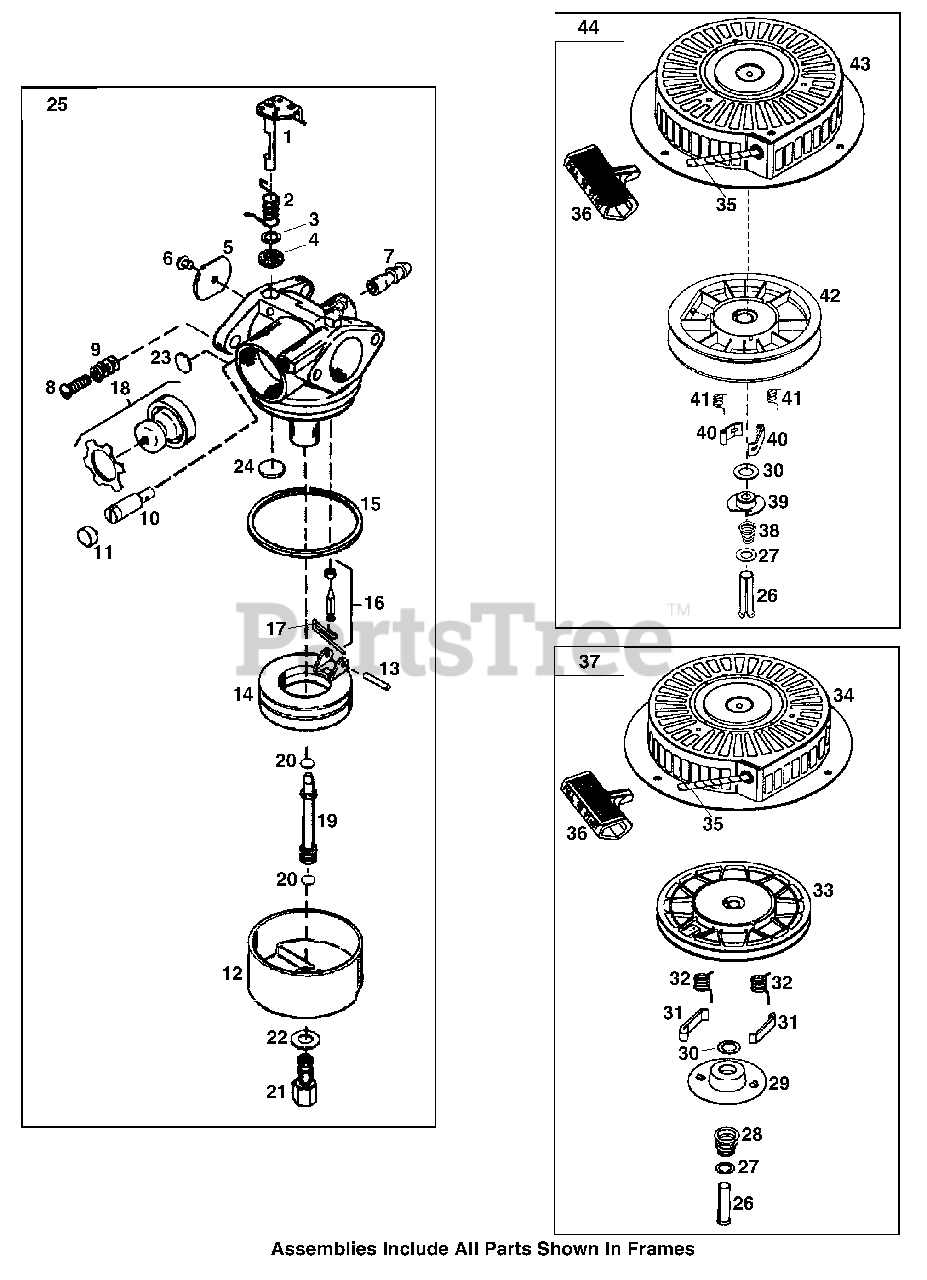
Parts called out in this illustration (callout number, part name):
1	Throttle Shaft & Lever Ass’y
2	Throttle Return Spring
3	Dust Seal Washer
4	Dust Seal (Throttle)
5	Throttle Shutter
6	Shutter Screw
7	Fuel Fitting
8	Throttle Crack/Idle Speed Screw
9	Tension Spring
10	Idle Restrictor Screw
11	Idle Restrictor Screw Cap
12	Float Bowl
13	Float Shaft
14	Float
15	Float Bowl "O" Ring
16	Inlet Needle, Seat & Clip
17	Spring Clip
18	Primer Bulb/Retainer Ring
19	Main Nozzle Tube
20	Main Nozzle Tube "O" Ring
21	High Speed Bowl Nut
22	Bowl Nut Washer
23	Welch Plug, Idle Mixture Well
24	Welch Plug, Atmospheric Vent
25	Carburetor Assembly
26	Spring Pin
28	Brake Spring
31	Starter Dog
32	Dog Spring
33	Pulley & Rewind Spring Ass’y
34	Starter Housing Ass’y
35	Starter Rope (98")
36	Starter Handle
37	Rewind Starter Ass’y
38	Brake Spring
40	Starter Dog
41	Dog Spring
42	Pulley & Rewind Spring Ass’y
43	Starter Housing Ass’y
44	Rewind Starter Ass’y
